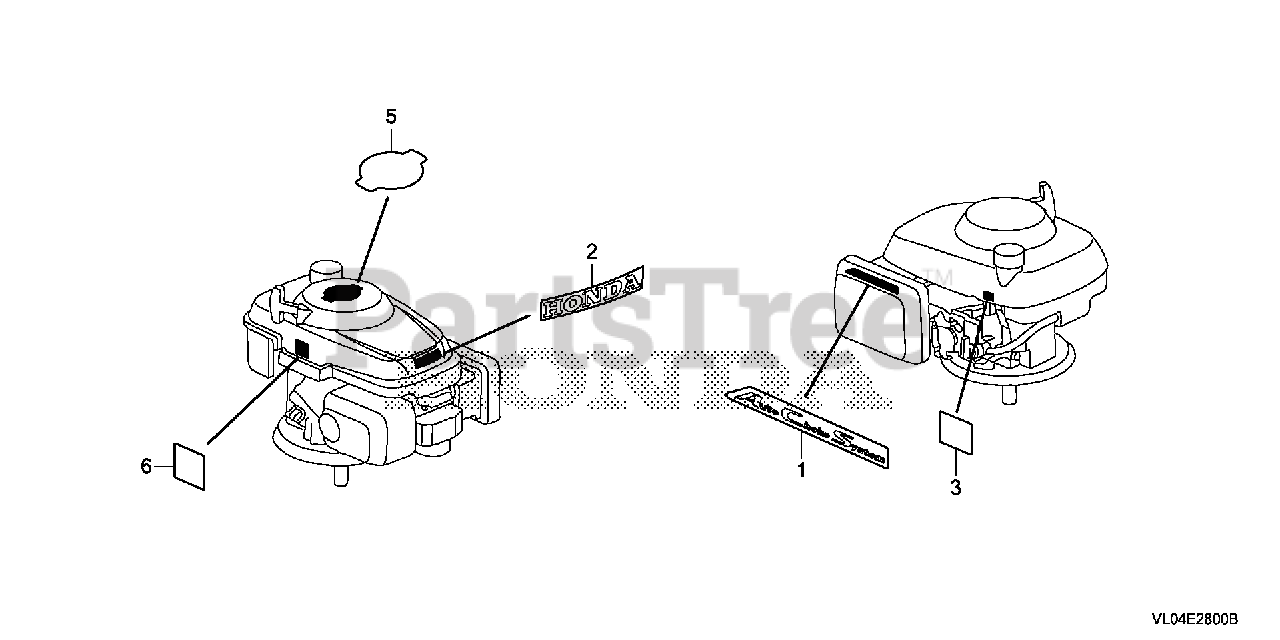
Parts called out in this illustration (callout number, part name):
2	MARK, HONDA (TYPE1)
3	MARK, FUEL PETCOCK CAUTION
5	MARK, RECOIL COVER
